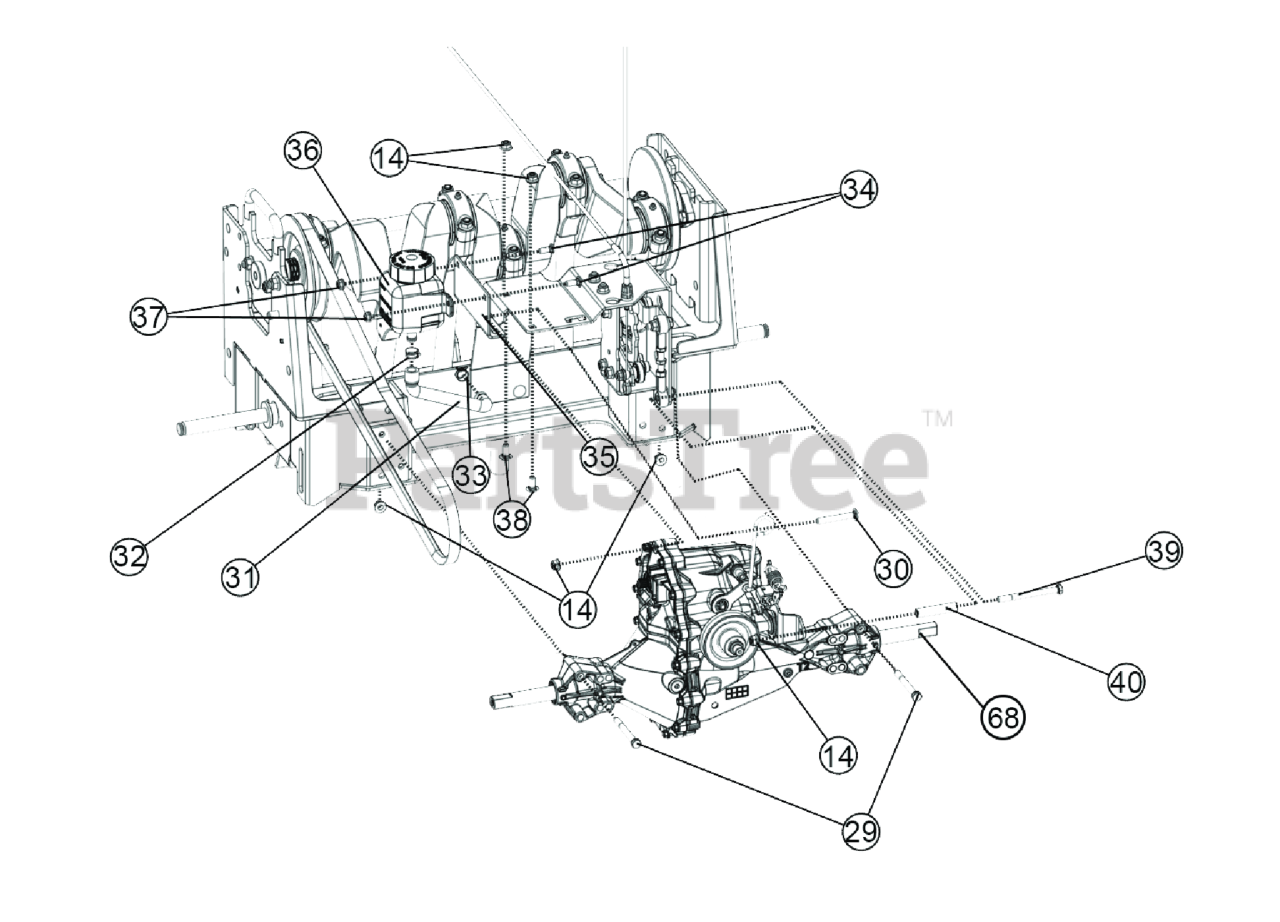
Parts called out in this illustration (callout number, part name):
14	NUT-HEX-NYLK, FLG .3125-18 ZP
29	SCREWCAP 5/16"-18 X 3" HCS ZP
30	BLT-RDHDSSQNK, .3125"-18 X 2.250 G5 YZ
31	HOSE, EXPANSION TANK
32	CLAMP, HOSE CTL Ø.645" ID X .030" THICK
33	CLAMP, HOSE CTL Ø.583" ID X .030" THICK
34	BOLT CARRIAGE 1/4" X 3/4"
35	PLATE, EXPANSION TANK MNT
36	TANK, EXPANSION
37	NUT-HEX-NYLK, FLG .250"-20 ZP
38	BOLT CARRIAGE 5/16-18 X 3/4" ZP SHRT NK
39	SCREWCAP 5/16"-18X3 1/2" HCS ZP
40	SPACER, .500" OD X 2.313" ZP
68	ASM, TRANSAXLE REPLACEMENT
